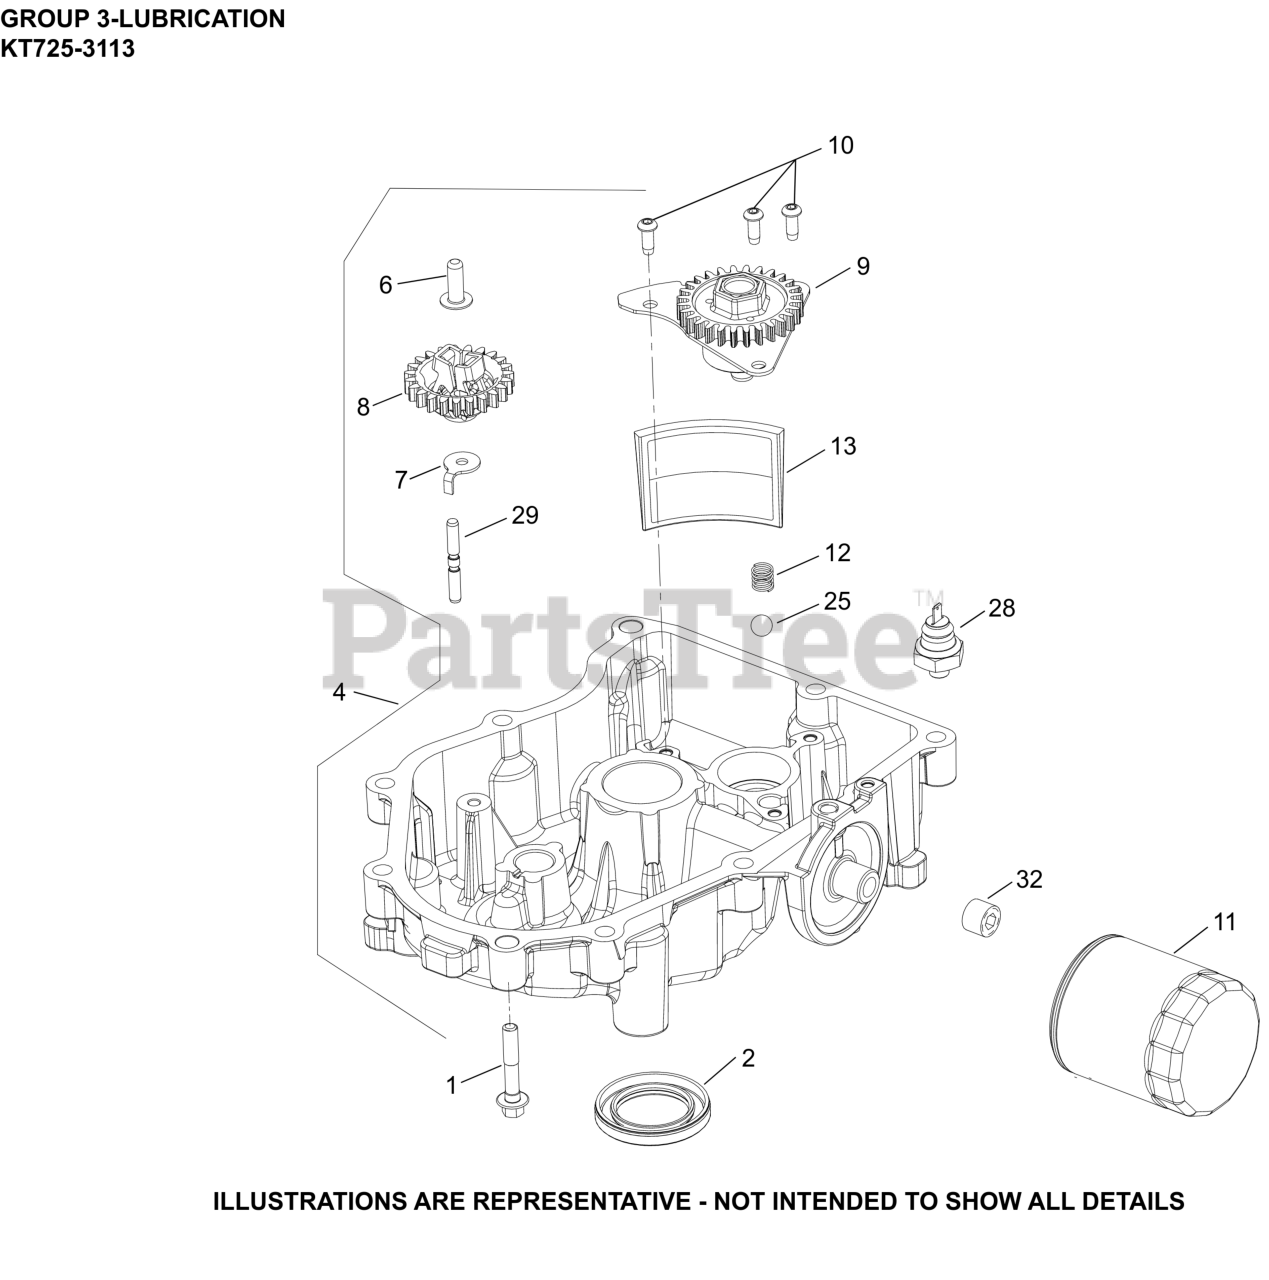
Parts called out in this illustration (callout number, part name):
1	SCREW, FLG M8X1.25X45
4	OIL PAN ASSEMBLY, (ROLLER BURNISHED)
6	PIN, GOVERNOR REGULATING
7	TAB, LOCKING
8	KIT, GOVERNOR GEAR
9	PUMP ASSEMBLY, OIL
10	SCREW, BUTTON HEAD
11	OIL FILTER
12	SPRING, COMPRESSION
13	SCREEN, OIL
25	PRESSURE RELIEF BALL
28	SWITCH, OIL PRESSURE(NC 3-6 PSI TO OPEN)
29	SHAFT, GOVERNOR GEAR
32	PLUG, PIPE CTSK 3/8"
